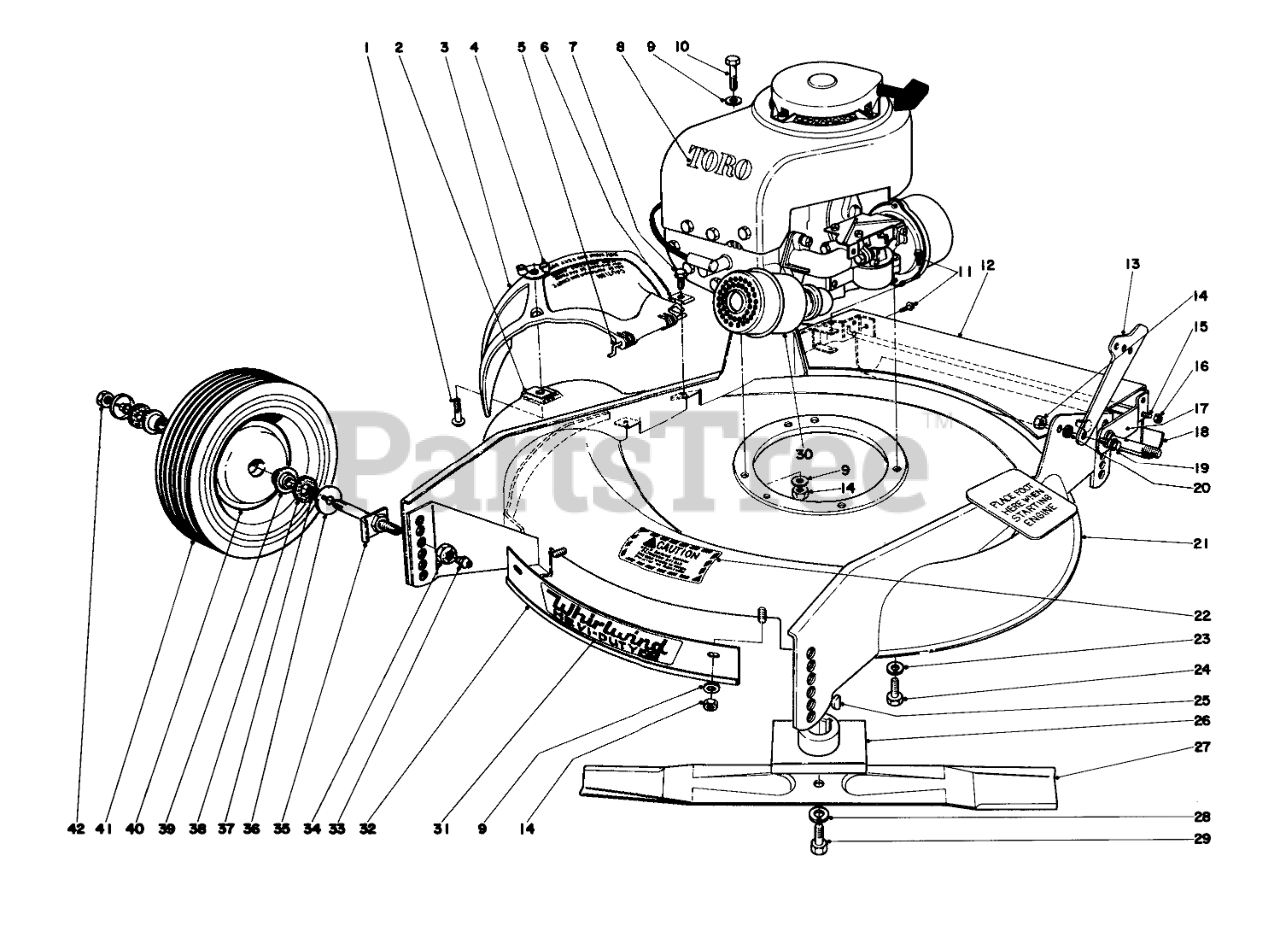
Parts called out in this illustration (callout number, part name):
2	NUT-SPEED
3	Deflector
4	NUT-WING SPECL
6	Clamp
7	1/4-20X1/2 THDG SEMS
8	DECAL
9	WASHER-PLAIN
10	SCREW-HH
11	10-16 X 3/8 THDG SCREW
12	Cover
13	Latch
14	Nut
15	Safety Shield Rod
16	NUT-LOCK, NI
18	REAR SAFETY SHIELD
19	SCREW-SHOULDER
20	SPACER
23	WASHER-LOCK
24	SCREW-HH
25	KEY-WOODRUFF
26	BLADE RETAINER WA
27	Blade
28	WASHER-LOCK
29	SPECIAL SCREW
31	Decal
33	FITTING-GREASE
34	NUT-LOCK, NI
35	Spindle Ass-y. (Incl. Ref. #29)
36	SLINGER
37	O-RING
38	Washer
39	BEARING-BALL
40	Wheel (Incl. Ref. #53)
41	1.75-8 SEMIPNEU TIRE
42	Nut
